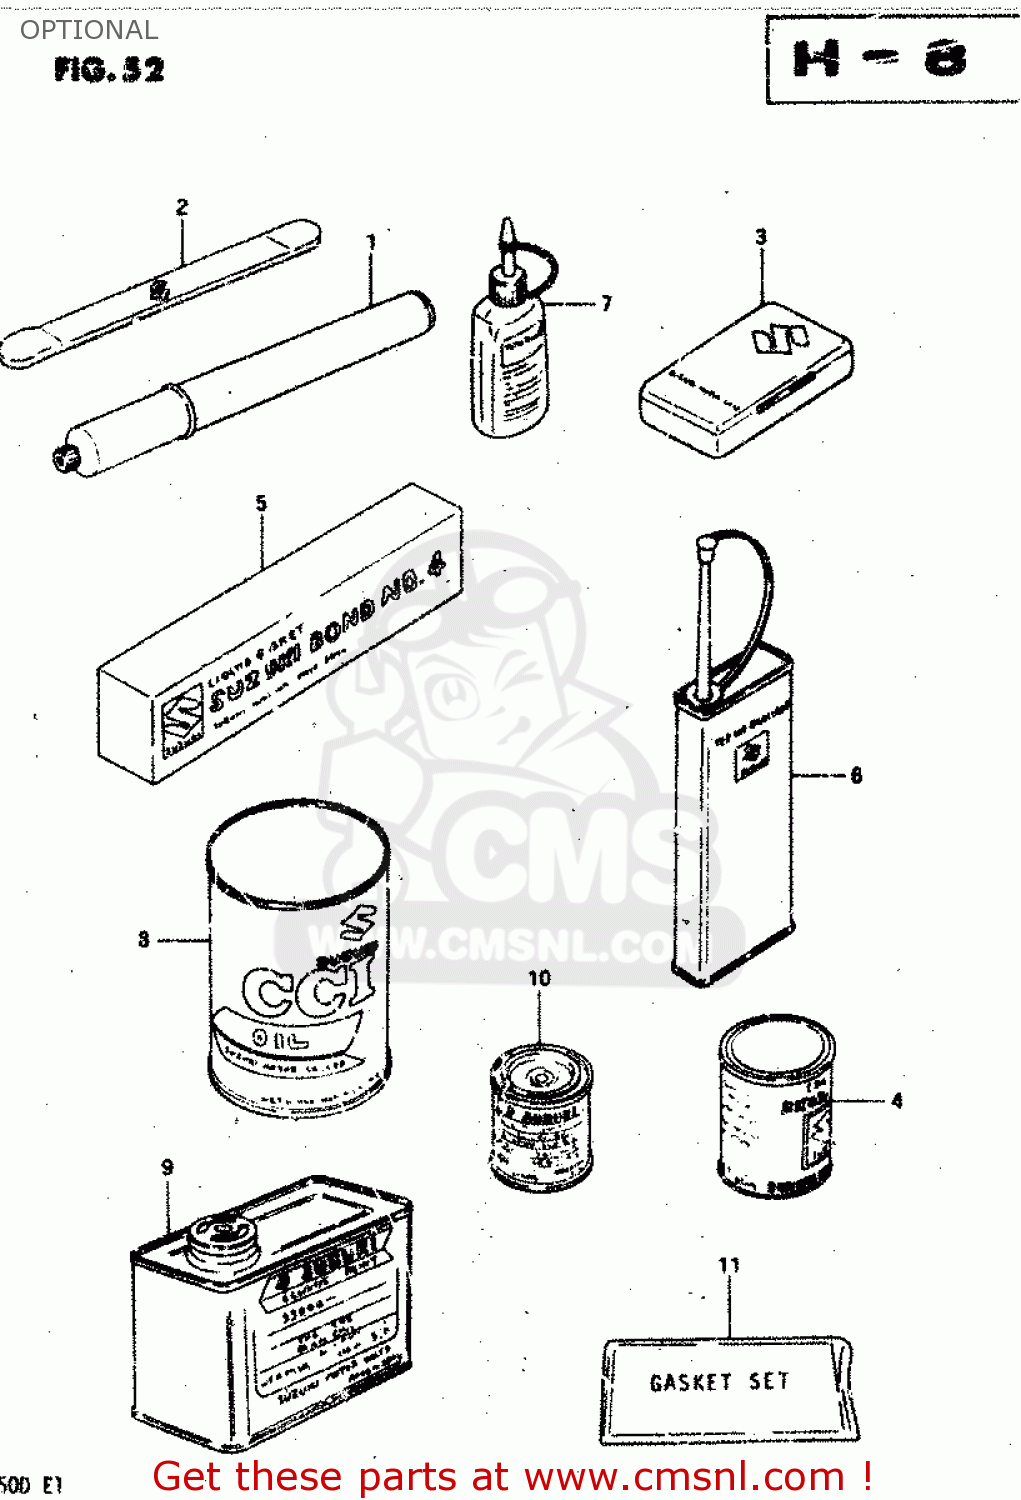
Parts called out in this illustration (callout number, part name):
1	INFLATOR, AIR
2	LEVER,TIRE
3	TUBE REPARING TOOL
4	GREASE(C)EP2 LITHIUM 150G
5	BOND 1104
6	THREAD LOCK NO.1401 CLEAR 200G
7	THREAD LOCK NO
8	CCI OIL
9	PAINT (BLACK)
10	PAINT,BLACK
11	GASKET SET
